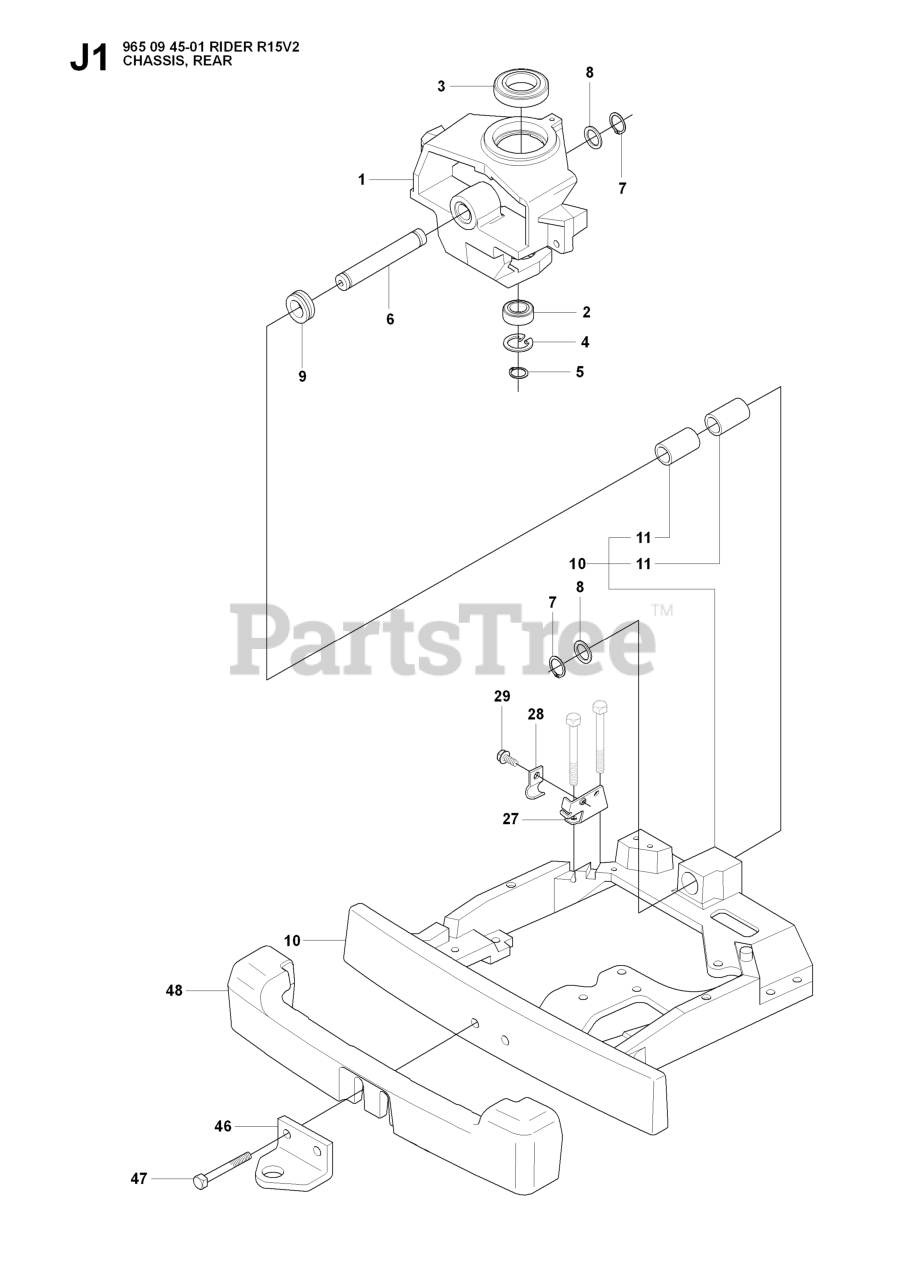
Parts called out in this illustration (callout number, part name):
2	Ball Bearing 6005-2rs
3	BALL BEARING 6010 2RS1
4	CIRCLIP SGH 47
5	RETAINING RING SGA 25
7	RETAINING RING SGA 25
47	REPL BY 725 25 00-71
48	COUNTERWEIGHT
